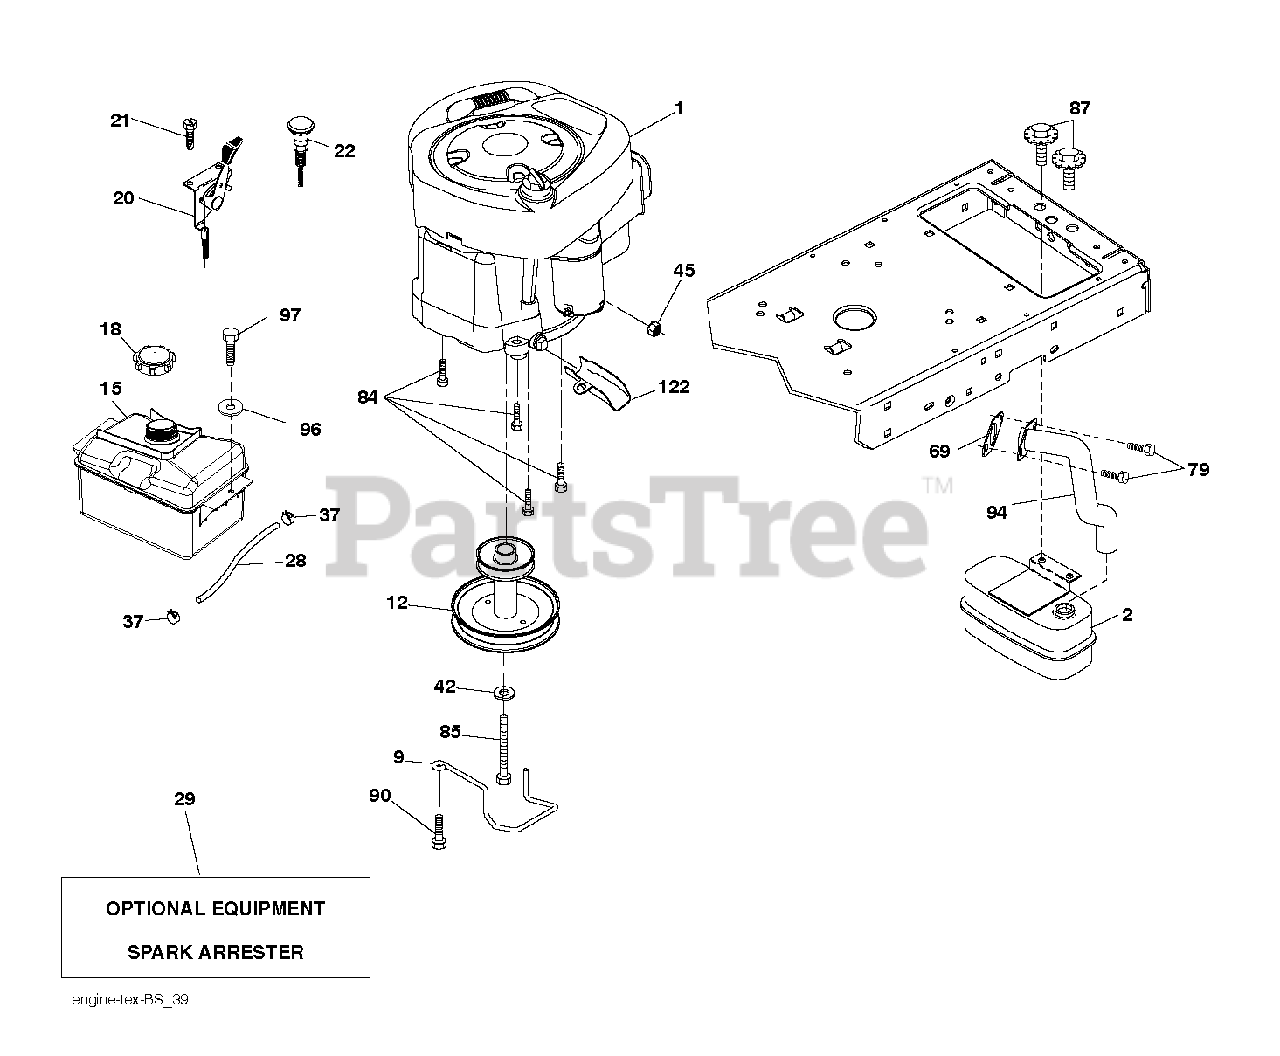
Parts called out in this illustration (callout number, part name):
2	MUFFLER.SINGLE.CYL.KOHL/B&S
9	KEEPER.BELT.ENGINE.4.2
12	PULLY ENGINE
15	TANK FUEL FRT 1.5 GAL
18	CAP ASM.FUEL.2.25"FR.
20	CONTROL.TH/CK.C.
21	SCREW.#10 X 0.750.BOS THREAD
28	LINE.FUEL.20
29	ARRESTER SPARK (OPTIONAL)
37	HOSE CLAMP
42	LOCKWASHER
45	NUT
69	REPL BY 532 27 22-93
79	SCREW.SOCKET HD.5/16-1
84	SCREW.3/8-16
85	BOLT HEX 7/16-20X4-1/4"
87	BOLT, 5/16-18 X 1 3/4
90	SCREW 3/8-16X1
94	EXHAUST.TUBE.B&S.
97	SCREW HEXWSHR 1/4-20X3/4
122	EXTENSION DRAIN OIL
